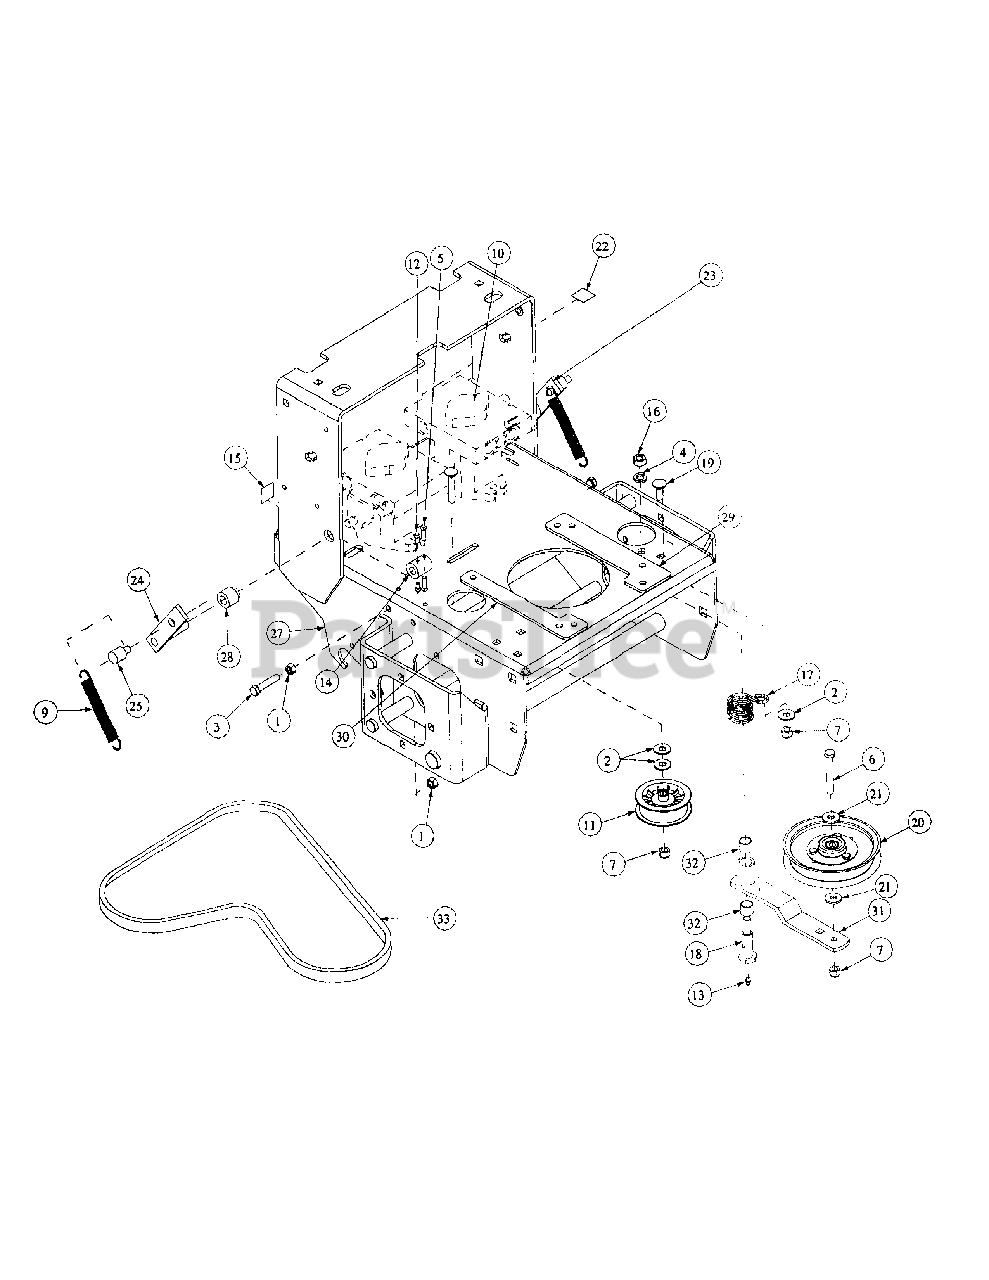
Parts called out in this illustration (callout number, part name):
1	Nut, Hex, 3/8-16
2	Flat Washer, USS 3/8
3	Cap Screw, 3/8-16 x 1-3/4"
4	Wash, Lock, 7/16, Zinc
5	Screw, CP, Square Head Set, 1/4-20
6	HHCS, 3/8-16, 1
7	Nylon Insert, Lock Nut 3/8-16
8	Carriage Bolt 3/8-16 x 2
9	Wire Spring
10	Hydro Pump
11	Flat Idler Pulley with Adapter
12	Cap Screw, Square Head Set, 1/4-20
13	Grease Fitting, 1/4-28 x 3/16
14	Coupling, Trunnion
15	Decal, Made In America
16	Nut, Hex, 7/16-14
17	Spring Idler Torsion
18	Shoulder Bolt
19	Carriage Bolt, 3/8-16 x 2
20	Pulley Assembly, Idler, 5.00"
21	Flat Washer, .406 ID: 1.0 OD: .105
22	Label, Mower, Warn, Open Belt Drive
23	Hydro Pump Lever Assembly, LH
24	Hydro Pump Lever Assembly, RH
25	Pivot, Belt Tightener
27	Engine Base Assembly, Hydro WT
28	Bushing Lever Pump
29	Spacer Engine, RH
30	Spacer Engine, LH
31	Idler Arm with bearings
32	Bearing sleeves
